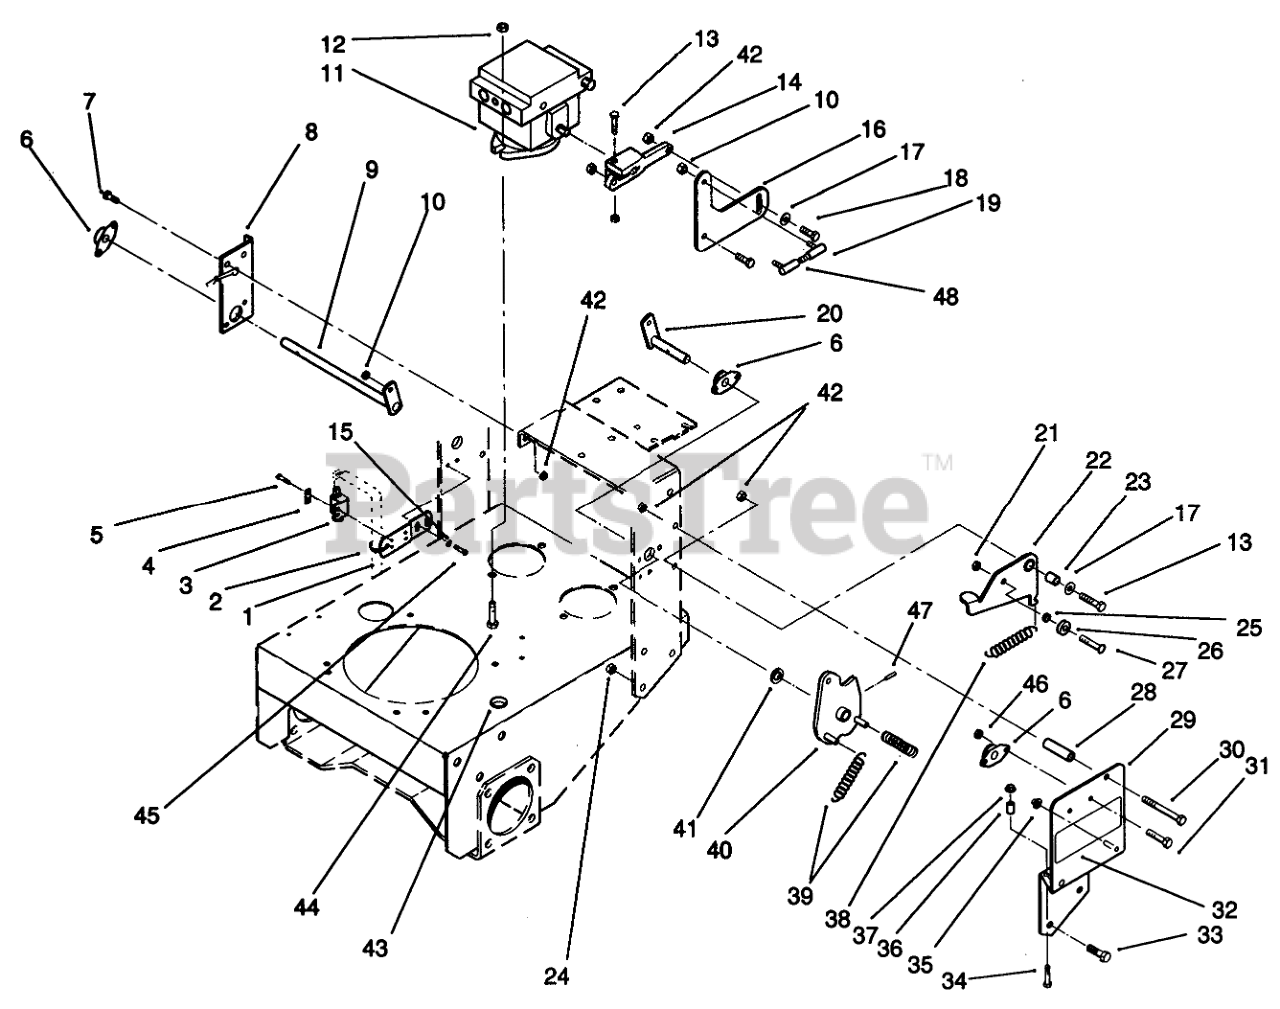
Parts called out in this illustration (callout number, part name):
1	NEUTRAL BRACKET B
2	TIE-CABLE
3	SWITCH-POLE, SINGLE
4	PLATE-SWITCH
5	SCREW-TAPTITE
6	SIDE FLANGE BEARING ASM
7	SCREW-HH
8	Bracket-Bushing
9	RH LEVER WA
10	NUT-LOCK, NI
11	HYDRAULIC PUMP
12	NUT-HF
13	SCREW-HH
14	ARM-PUMP
15	WASHER-FLAT
16	FOLLOWER ARM B
17	WASHER-FLAT
18	SCREW-HH
19	1/2-20 BALL JOINT ASM
20	LH LEVER WA
21	NUT-LOCK, NI
22	Detent Arm Assembly L.H.
23	BUSHING-ARM, DETENT
24	NUT-LOCK, NI
25	SPACER-BEARING
26	BEARING-BALL
27	SCREW-HSBH
28	STOP-REVERSE
29	LEFT BRACKET WA R
30	SCREW-HH
31	SCREW-HH
32	DECAL-HYDRO
33	SCREW-HH
34	SCREW-HH
35	NUT-PUSH
36	SPACER-TUBULAR
37	NUT-LOCK, HHF
38	SPRING-DETENT
39	Spring
40	Pivot Assembly L.H.
41	WASHER-THRUST
42	NUT-LOCK, NI
43	GROMMET
44	SCREW-HH
45	SCREW-HWH
46	NUT-LOCK, NI
47	PIN-ROLL, SLOTTED
48	BALL JOINT ROD
